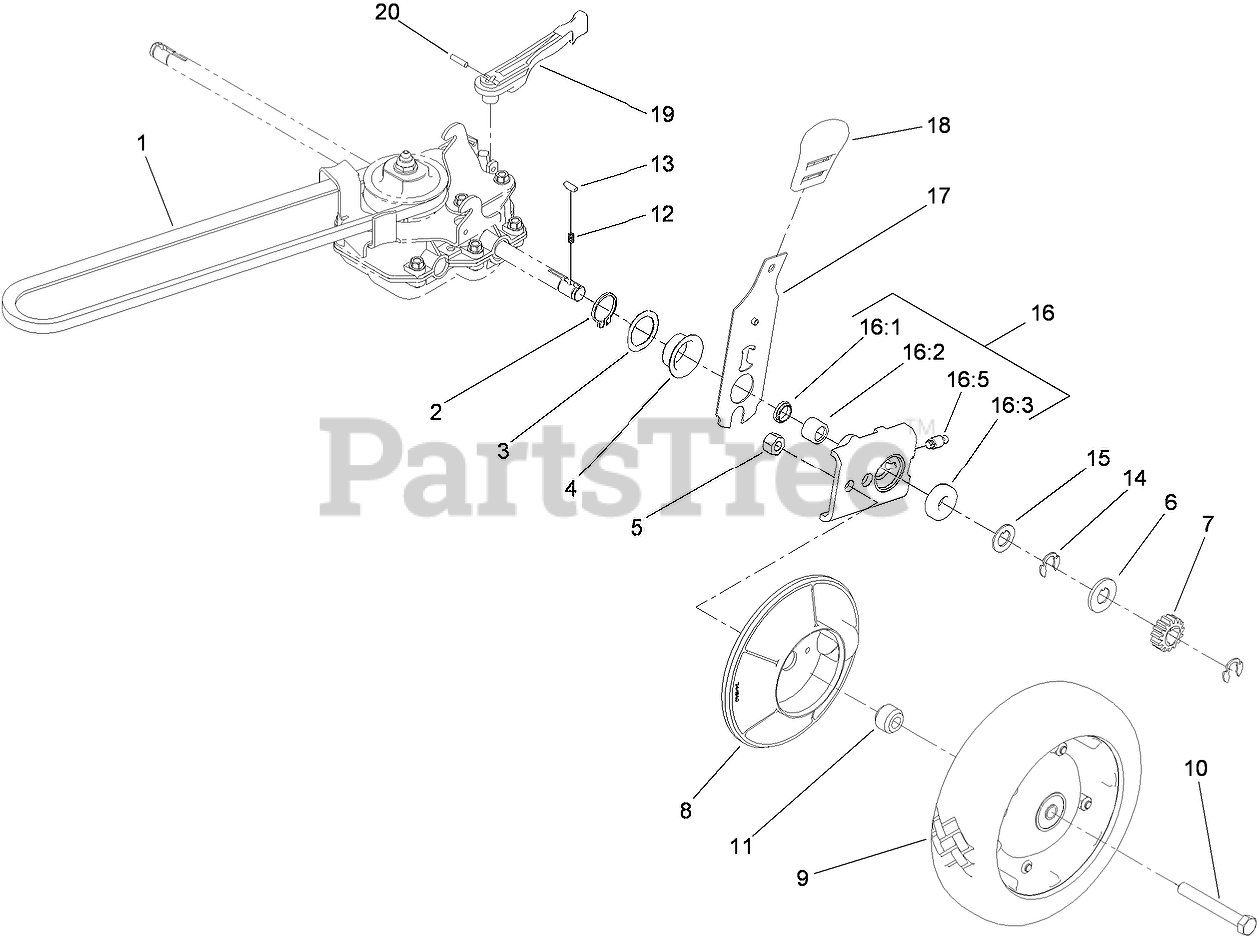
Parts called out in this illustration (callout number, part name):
1	V-BELT
2	RING-RETAINING
3	WASHER
4	CAP-END
5	NUT-LOCK, CONE
6	WASHER-THRUST, OUTER
7	GEAR-PINION
8	COVER-WHEEL
9	Wheel And Tire ASM
10	SCREW-HH
11	SPACER-COVER, WHEEL
12	SPRING-COMPRESSION
14	RING-RETAINING
15	WASHER-THRUST, OUTER
16	PIVOT ARM ASM
16:1	SEAL-OIL
16:2	BEARING-CAGED NEEDLE ROLLER
16:3	BEARING-WHEEL
17	REAR SPRING ARM ASM
18	KNOB-HOC
19	LEVER-SHIFT
20	PIN-COIL
